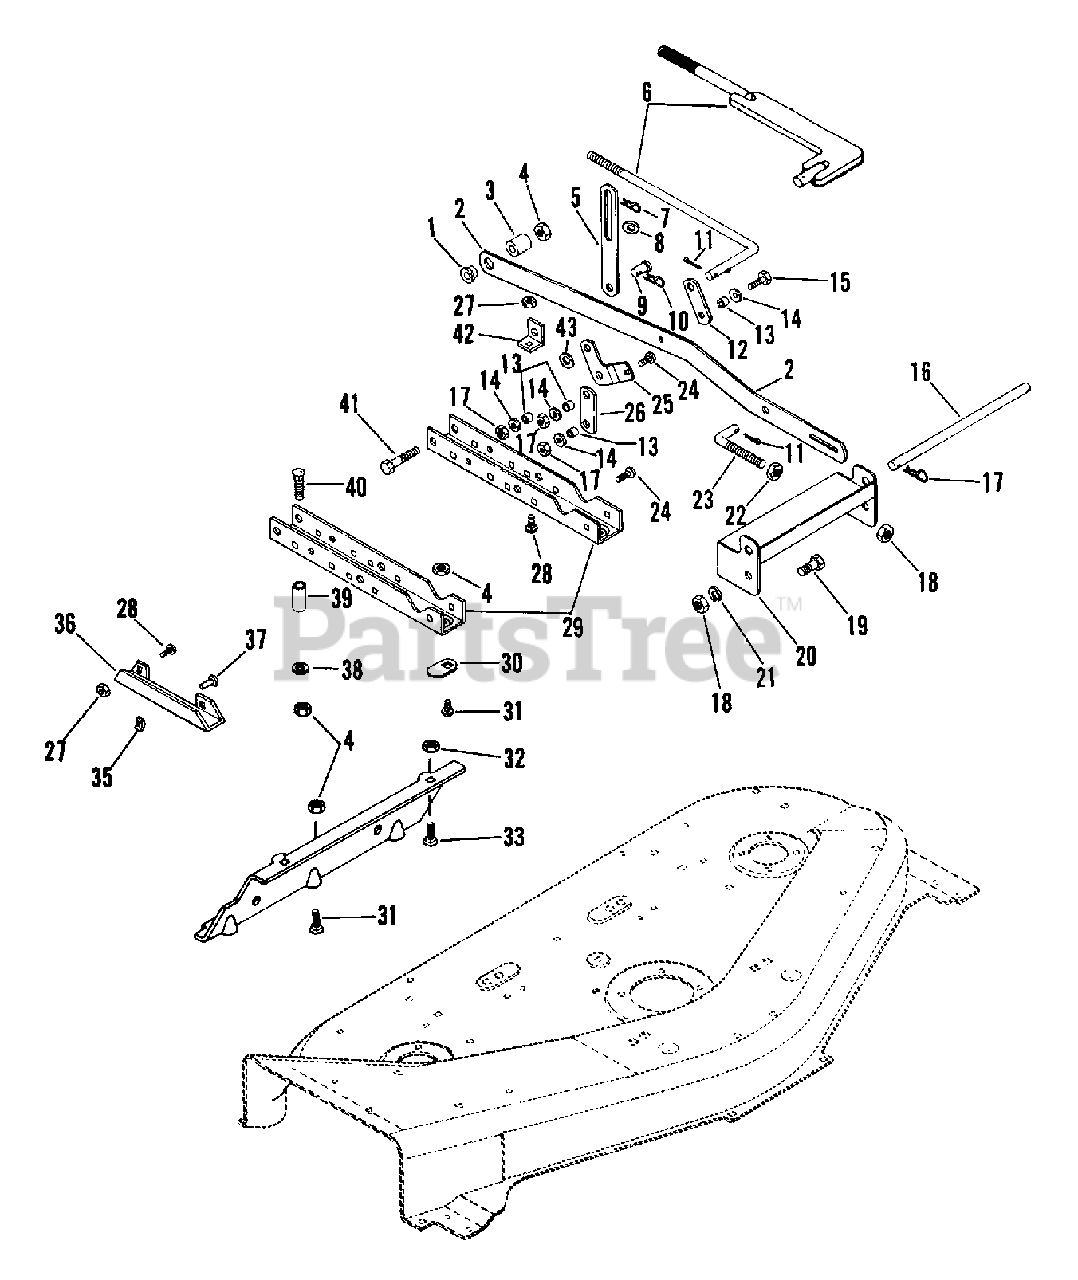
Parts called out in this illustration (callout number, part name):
1	BSHG-FLG .531X.750X.562X1.000
2	HANGER BAR
3	SPACER .531X1.000X1.188
4	NUT-LK-CTR .50-13
4	NUT-LK TOP .375-16 GR C YWZC
5	LIFT LINK
6	ADJUSTMENT ROD
6	PITCH ADJUSTER
7	PIN-HAIR INT .09X.188 PL
8	WSHR-FL-STL .531X1.062X.095 PL
9	CLEVIS PIN
10	PIN-HAIR INT .08X.38X1.42 YWZC
11	PIN-COTR .12X1.0 PL
13	SPACER BUSHING .5 X .32 X .21
14	WSHR-FL-STL .328X.875X.062 PL
15	BLT-HEX .31-18X1.25 PL GR2
16	HINGE PIN
17	PIN-HAIR EXT .12X.31X2.37 PL
18	NUT .50-13 PL
19	BLT-RDHDSQNK .50-13X1.25 PL
20	PIVOT BRACKET
21	WSHR-LK .500X.151 HVY PL
22	NUT-JAM .50-13 PL
23	ROD BELT ADJUSTMENT
24	BLT-RDHDSQNK .31-18X.75 SHT PL
25	R H ADJUSTMENT LEVER
25	L H ADJUSTMENT
26	ADJUSTMENT LINK
27	NUT-LK .312-18 GR A PL
28	BLT-RDHDSQNK .312-18X.62 PL
28	CHANNEL
29	CHANNEL
30	COVER
31	BLT-RDHDSQNK .50-13X.75 SHT PL
32	NUT-LK-CTR .375-16 GR A PL
33	BLT-RDHDSQNK .375-16X.75 PL
34	PLATE REAR MTG
34	PLATE-REAR MOUNTING
35	NUT-PUSH .312
36	BRACKET
37	RVT .312X.75 RH ST
38	WSHR-FL-STL .505X.880X.072 PL
38	WSHR-FL-STL .380X1.50X.125 PL
39	SPACER, PIVOT .500X.750X1.805
39	SPACER .512X.747X1.567
40	BLT-RDHDSQNK .50-13X2.50SHTPL
40	BLT-RDHDSQNK .38-16X2.75 GR5PL
41	BLT-HEX .50-13X2.50 PL GR5
42	BRACKET
43	WSHR-FL-STL .469X.937X.065 PL
44	NUT-LK-CTR .50-13
